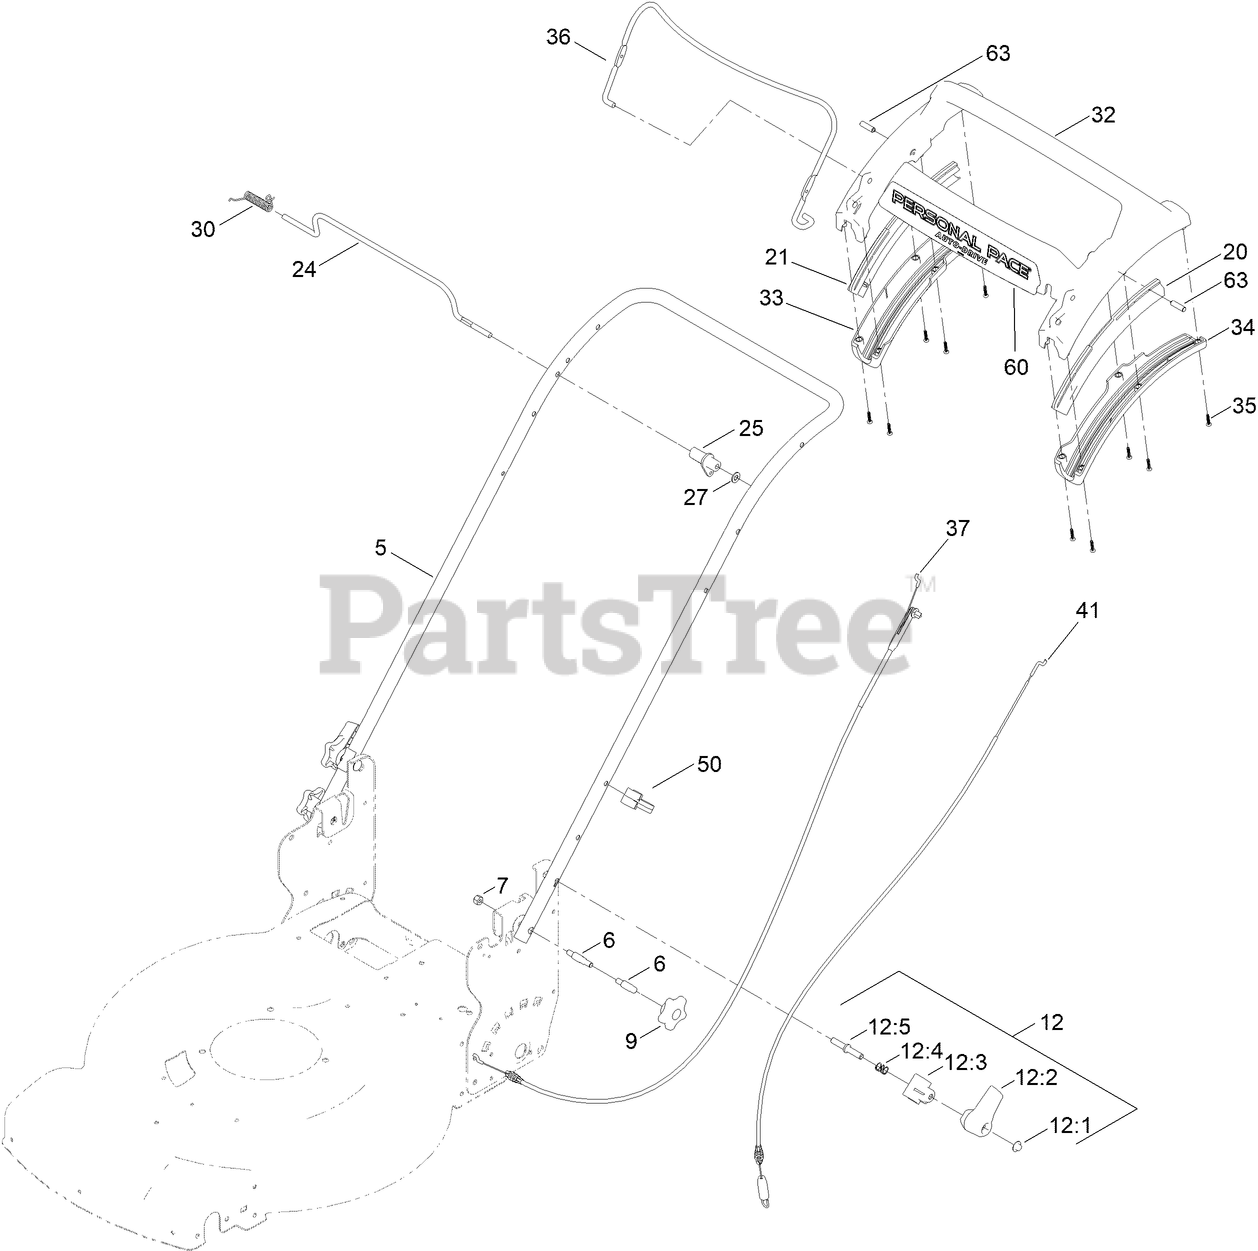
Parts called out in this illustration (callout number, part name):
5	HANDLE-CURVED
6	BOLT-SHOULDER, HANDLE
7	NUT-LOCK, NI
9	KNOB-HANDLE
12	QUICK RELEASE ASM
12:1	NUT-PUSH
12:2	LEVER-RELEASE
12:3	ANCHOR-SPRING
12:4	SPRING-COMPRESSION
12:5	ROD-RELEASE
20	GUIDE-CURVED, LH (RWD)
21	GUIDE-CURVED, RH (RWD)
24	ROD-CONTROL, TRACTION
25	LEVER-TRACTION, RWD
27	WASHER-PLAIN
30	SPRING-TORSION
32	HANDLE-PERSONAL PACE, CURVED
33	BOTTOM-HANDLE, RH
34	BOTTOM-HANDLE, LH
35	SCREW-PPH
36	BAIL-BRAKE
37	CABLE-BRAKE, PP BS
41	CABLE-TRACTION, RWD (PP)
50	GUIDE-CABLE
60	DECAL-60V, PERSONAL PACE
63	PIN-HANDLE, PP
